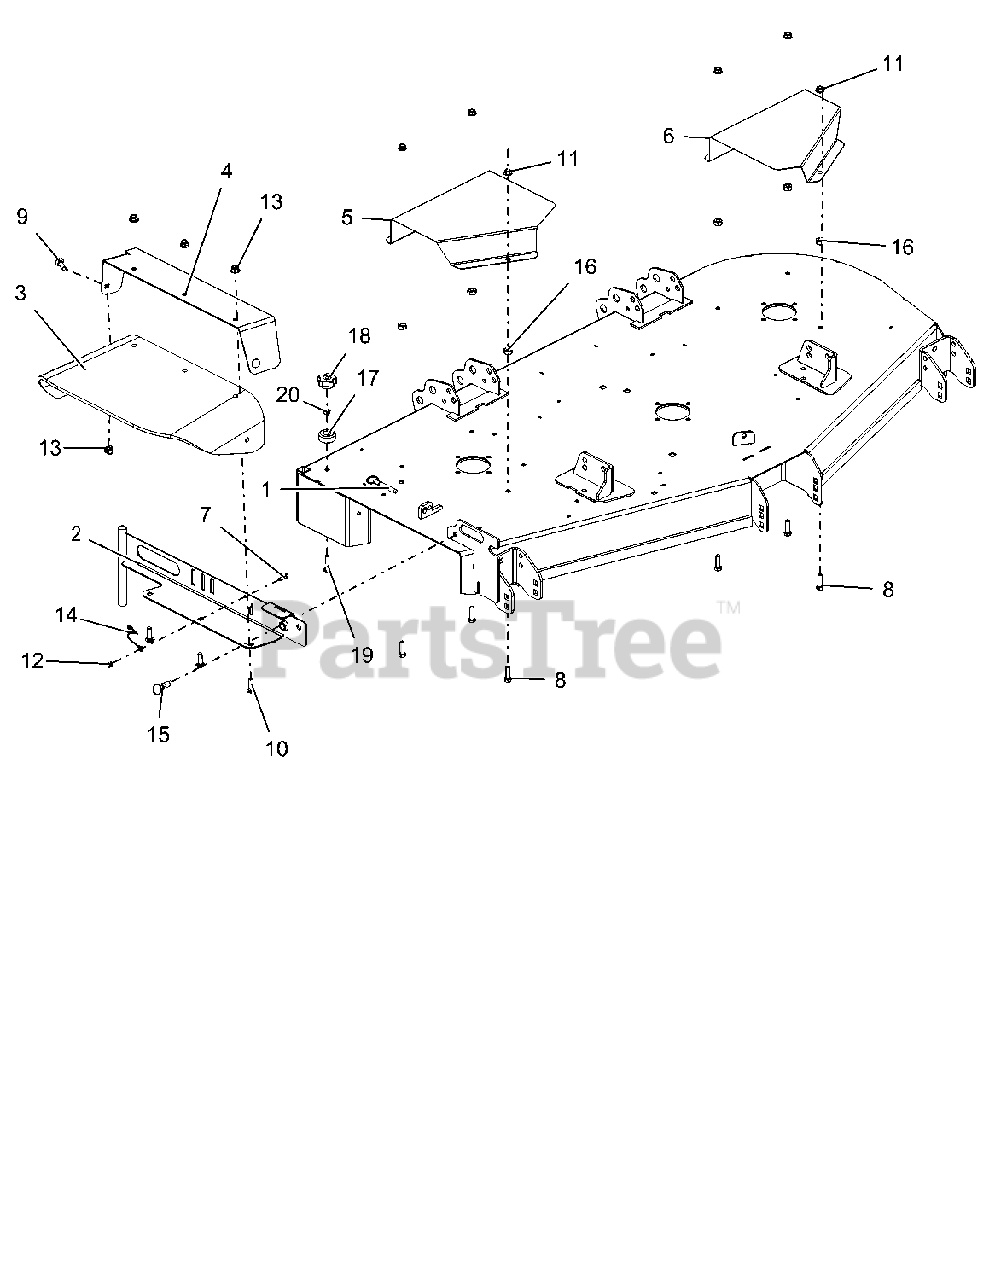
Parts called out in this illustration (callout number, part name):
1	PIN, SPRING BALL .375 OD X 1.50
2	WLDMT, DISCHARGE CHUTE 52"-60"
3	CHUTE, RUBBER DISCHARGE
4	SUPPORT, CHUTE MOUNTING BRKT
5	GUARD, DECK 60"-66" RH
6	GUARD, DECK 60"-66" LH
7	BLT-HEX .25-20X.75 GR5 YWZC
8	BLT-HEX .38-16X1.25 GR5 YWZC
9	BLT-RDHDSQNK .38-16X1.00 G5 YWZC
10	BLT-RDHDSQNK .38-16X1.25 G5 YWZC
11	@NUT-SPNLK-FLG .375-16 YWZC
12	NUT, LK-TOP-FLG .25-20 YWZC
13	NUT-LK-NYL-FLG .38-16 YWZC
14	CABLE, 6.0 LANYARD, NYLON
15	PULL PIN,.50-13THDX.310 PLNGR
16	NUT-HEAVY HEX .38-16 YWZC
17	BUMPER, RECESSED 1.50 X .63 W/.31 HOLE
18	KNOB, CLAMPING
19	BLT-RDHDSQNK .31-18X1.50 G5 YWZC
20	NUT-LK-CTR .31-18 YWZC
